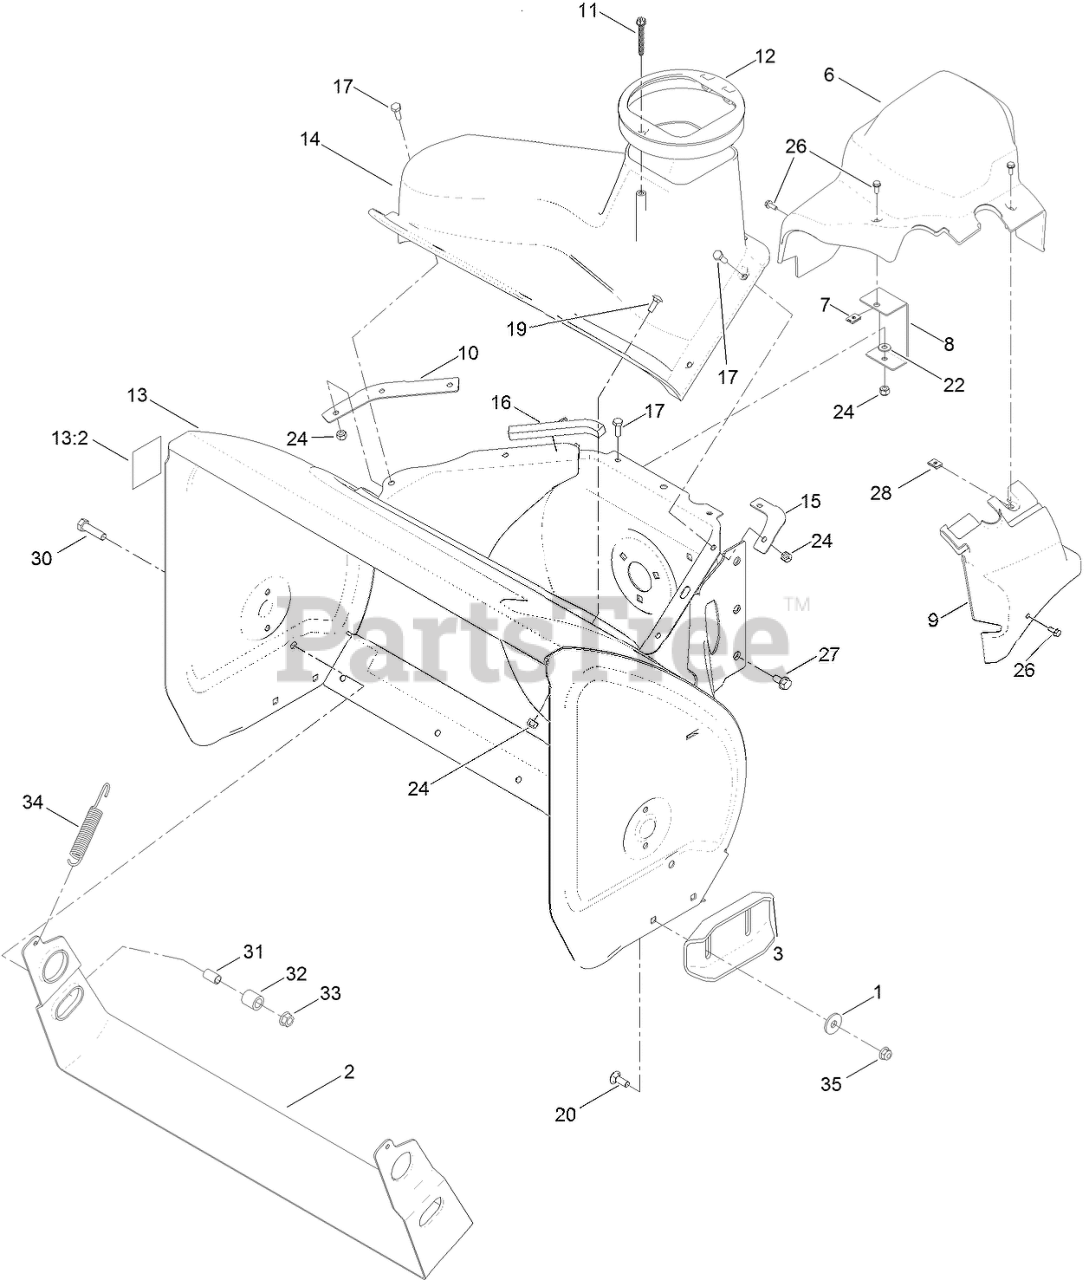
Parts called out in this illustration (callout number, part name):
1	WASHER
2	SCRAPER-PIVOTING, 28 INCH
6	COVER-BELT
7	NUT-SPEED, U-TYPE
8	BRACKET-COVER, CLIP NUT
9	COVER-EXTENSION, BELT
10	SEAL-FLANGE, COVER
11	SCREW-HWH, PLASTITE
12	GUIDE-CHUTE
13	HOUSING-AUGER, 28 INCH
13:2	DECAL-DANGER, AUGER
16	SEAL-HOUSING
17	SCREW-HH
19	BOLT-CARR
20	SCREW-CARR
22	WASHER-FLAT
24	NUT-LOCK, NI
26	SCREW-HWH
27	SCREW-HWHTF
28	NUT-SPEED
30	SCREW-HH
31	SPACER-SCRAPER, STOP
32	CUSHION-SCRAPER, STOP
33	NUT-HF
34	SPRING-SCRAPER
35	NUT-HF, NI
